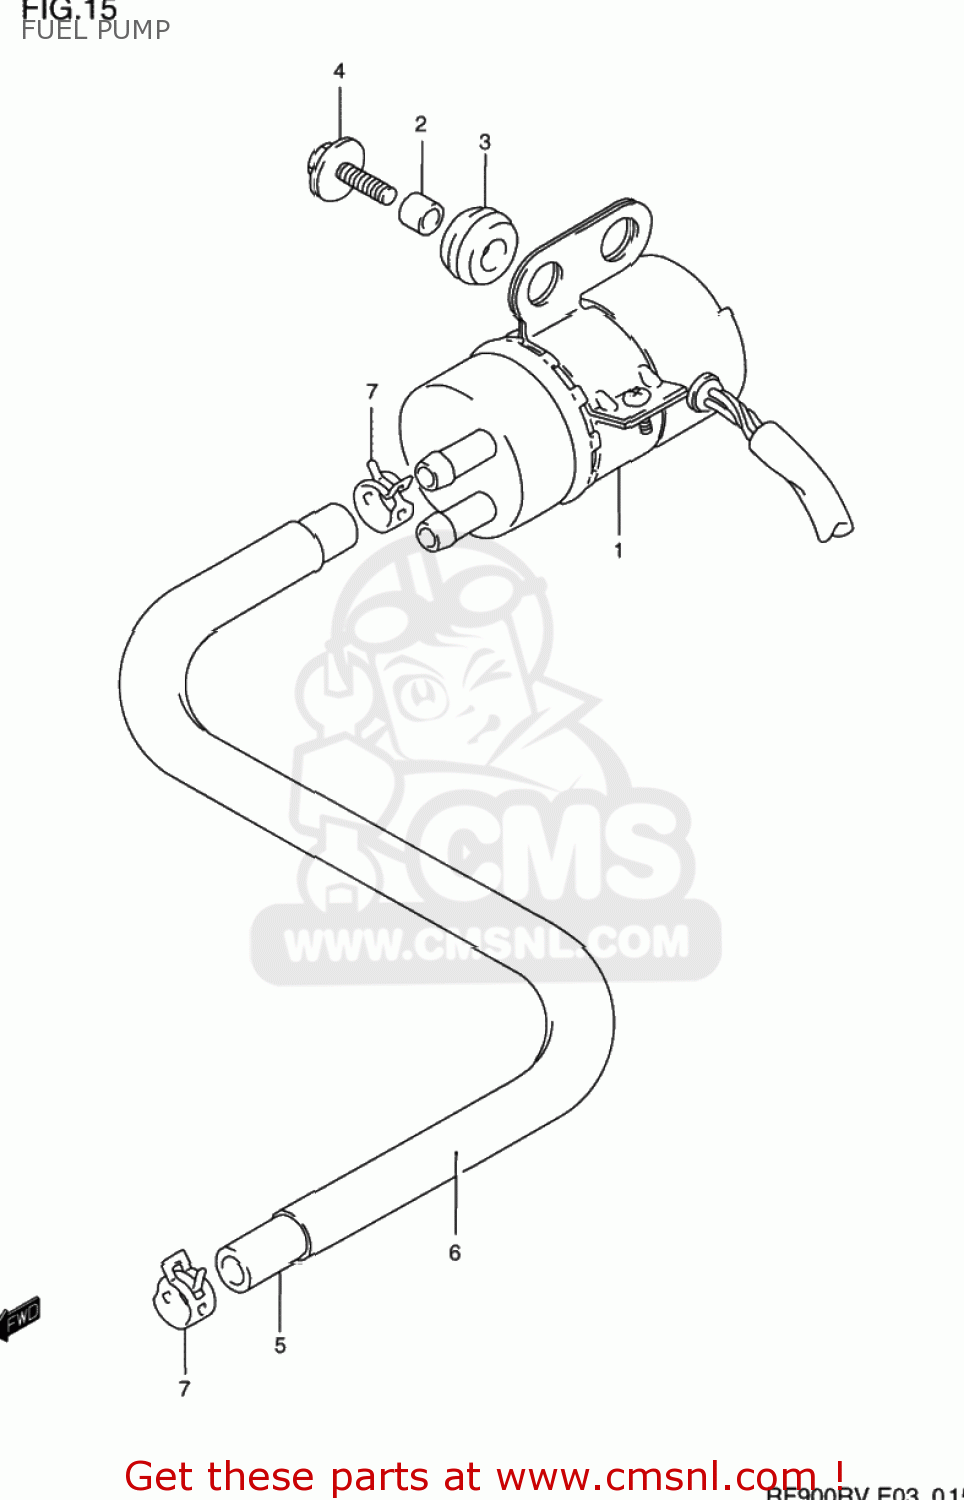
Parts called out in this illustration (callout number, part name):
1	PUMP ASSY,FUEL
2	SPACER(6.5X9X9)
3	CUSHION
4	BOLT(6X20)
5	HOSE(7X12X600)
6	PROTECTOR(14.5X15.5X600)
7	CLIP
